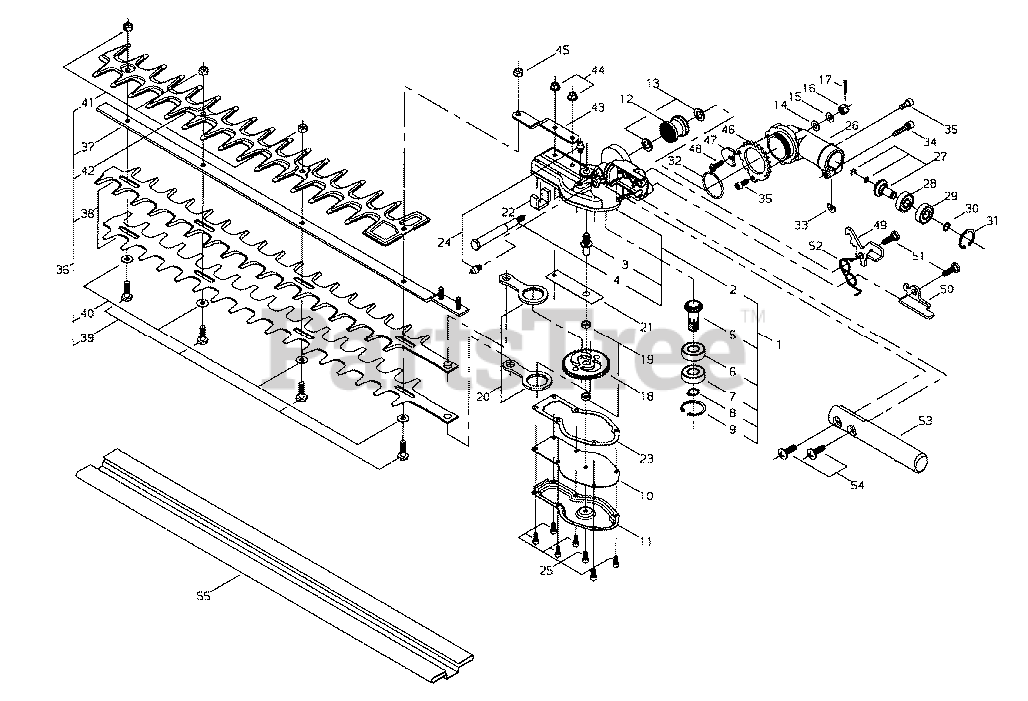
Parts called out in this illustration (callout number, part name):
1	GEAR CASE HOUSING KIT
2	GEAR CASE HOUSING ASSY
3	MAINSHAFT
4	SHAFT
5	SHAFT, PINION
6	BEARING, BALL 6001
7	BEARING, BALL 6001ZZ
8	RING, SNAP Ø12
9	RING, SNAP Ø28
10	SPACER
11	COVER, GEAR CASE
12	GEAR, BEVEL
13	COLLAR Ø16ר10×L= 2
14	WASHER 6.5×13×1
15	WASHER, CONE M6
16	NUT M6
17	PIN, COTTER Ø1.6×15
18	GEAR, CAM
19	SPACER Ø11ר8×3.4
20	CONROD
21	PLATE, GUIDE
22	PACKING, FELT
23	GASKET, GEAR CASE
24	FITTING, GREASE
25	BOLT 4×10
26	HOUSING, UPPER GEAR CASE
27	PINION SET, BEVEL
28	BEARING, BALL 609
29	BEARING, BALL 609ZZ
30	RING, SNAP
31	RING, SNAP Ø24
32	O-RING
33	D-WASHER
34	BOLT M5×25
35	BOLT 5×12
36	CUTTER ASSY, 22" CHROME
37	GUIDE BAR 22"
38	CUTTER, CHROME 22"
39	BOLT M6×20
40	WASHER M6
41	NUT, LOCK M6
42	GUARD, CUTTER BLADE
43	BRACKET, CUTTER
44	NUT, FLANGE M5
45	NUT, LOCK M6
46	RING, LOCKING
47	PLATE, STOPPER
48	SCREW
49	LEVER, LOCK
50	RELEASE, LOCK
51	BOLT M6
52	SPRING, TORSION
53	LEVER, ADJUSTMENT
54	SCREW, TRUSS M6×20
55	SCABBARD
